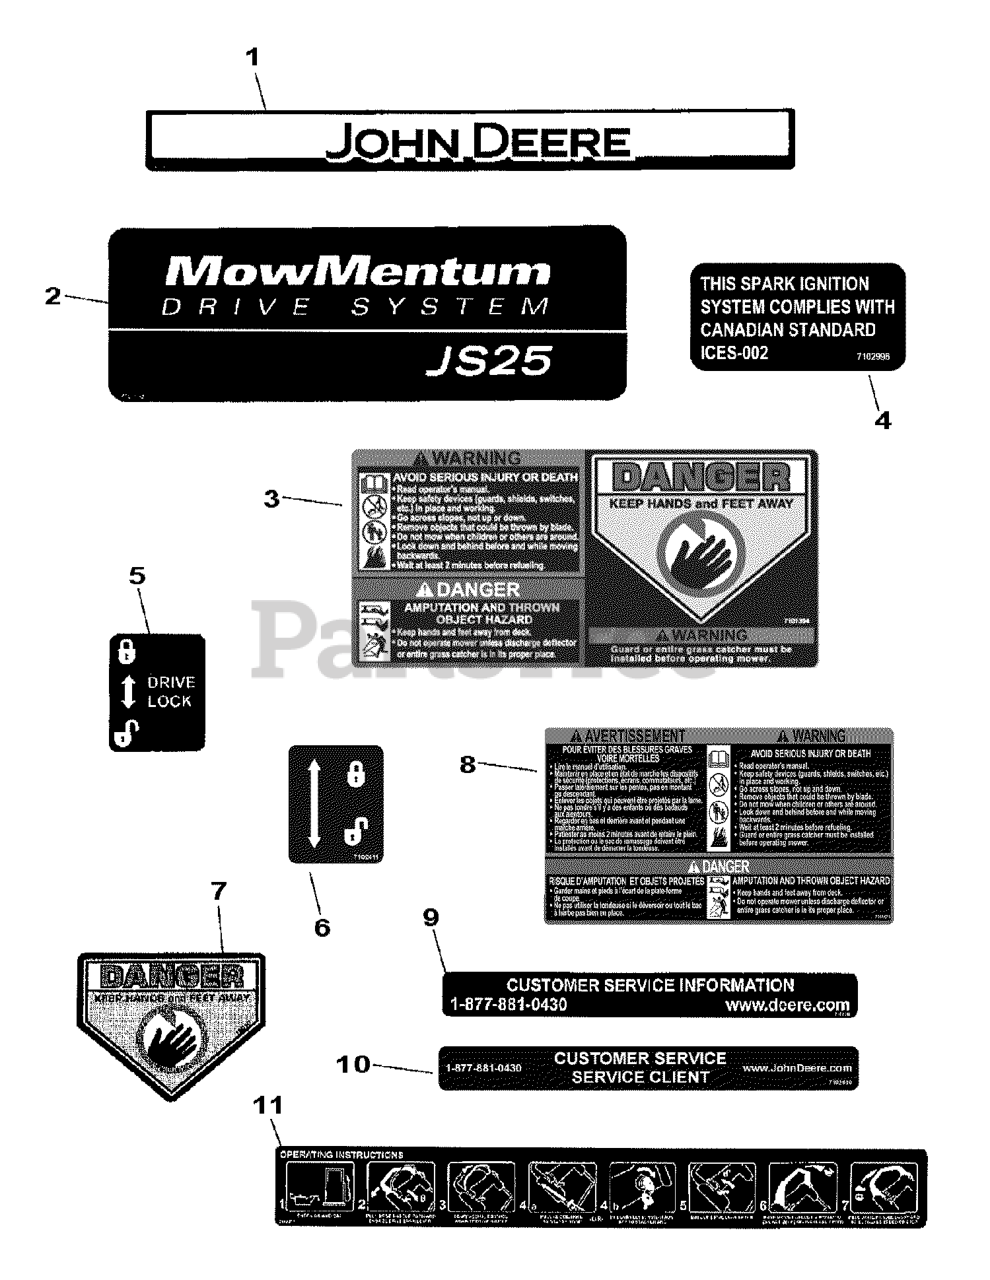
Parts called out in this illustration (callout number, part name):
1	DECAL, FRONT, JS25/35
2	DECAL, MOWMENTUM, JS25
3	DECAL, WARNING, REAR DISCHARGE DOOR
4	DECAL, COMPLIANCE, ICES
5	DECAL, NEUTRAL LOCK
6	DECAL, NEUTRAL LOCK, FC
7	DECAL, DANGER, CUT FINGER
8	DECAL, FRENCH/ENGLISH, WB SAFETY
9	DECAL, CUSTOMER SERVICE, MY08, DEERE
10	DECAL, CUSTOMER SERVICE, DEERE, FRENCH
11	DECAL, OPERATION, JD
